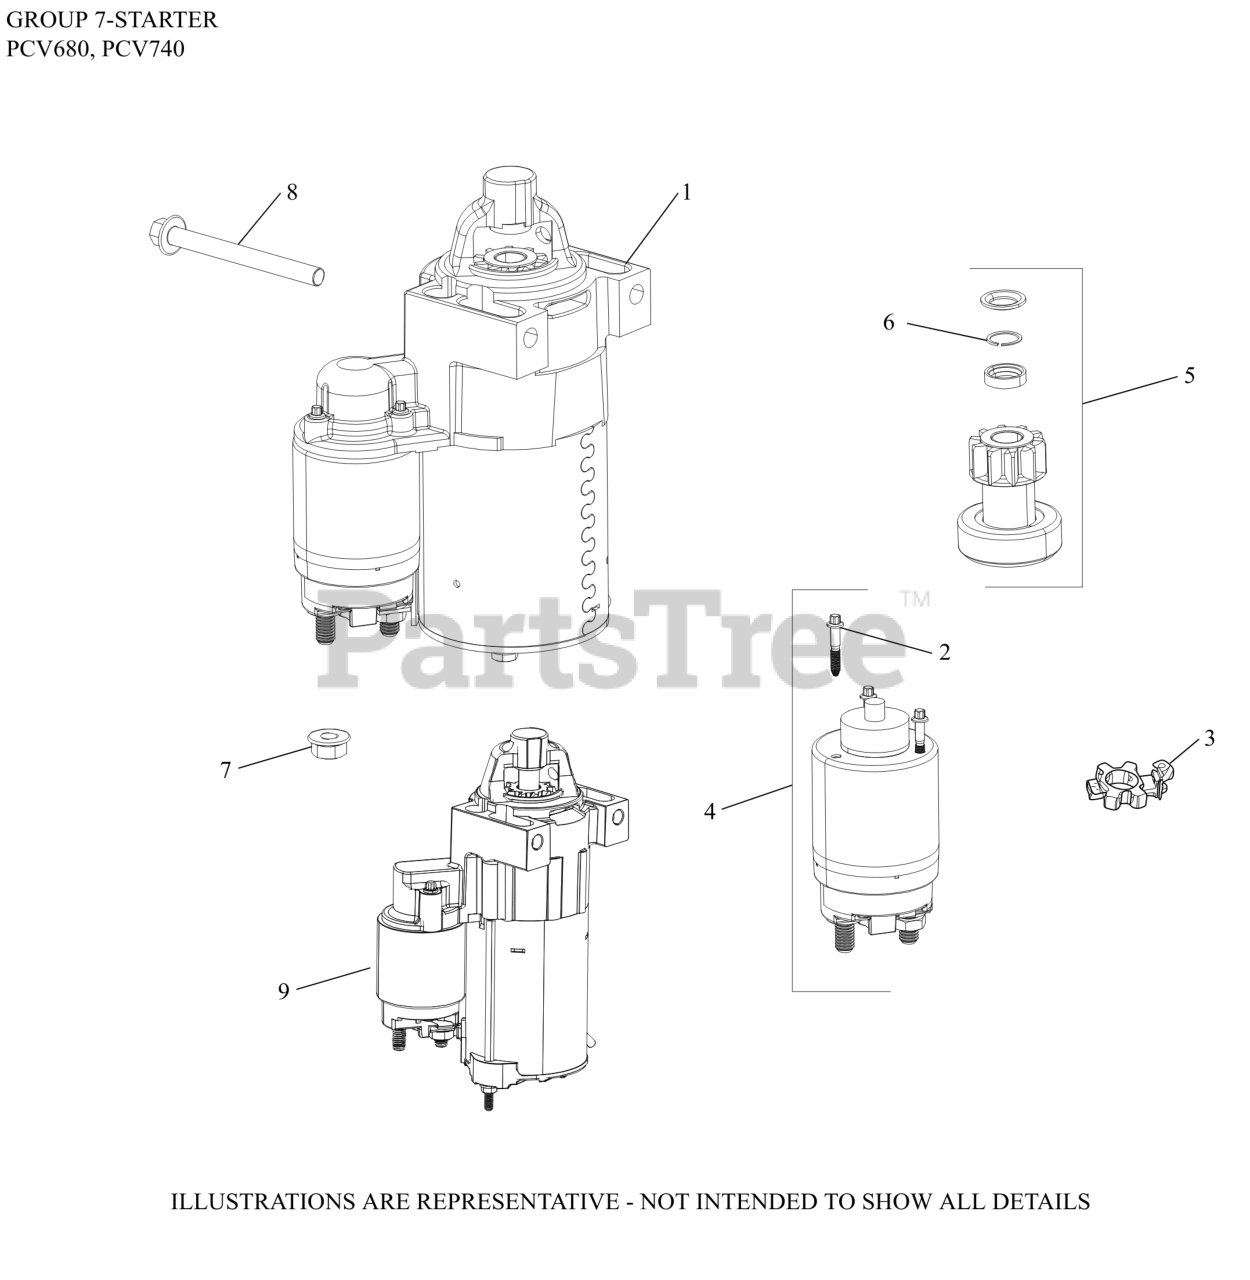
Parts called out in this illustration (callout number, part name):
1	STARTER, SOLENOID SHIFT-(#2509824S)
7	NUT, FLG M8X1.25
8	SCREW, FLG M8X1.25X80
